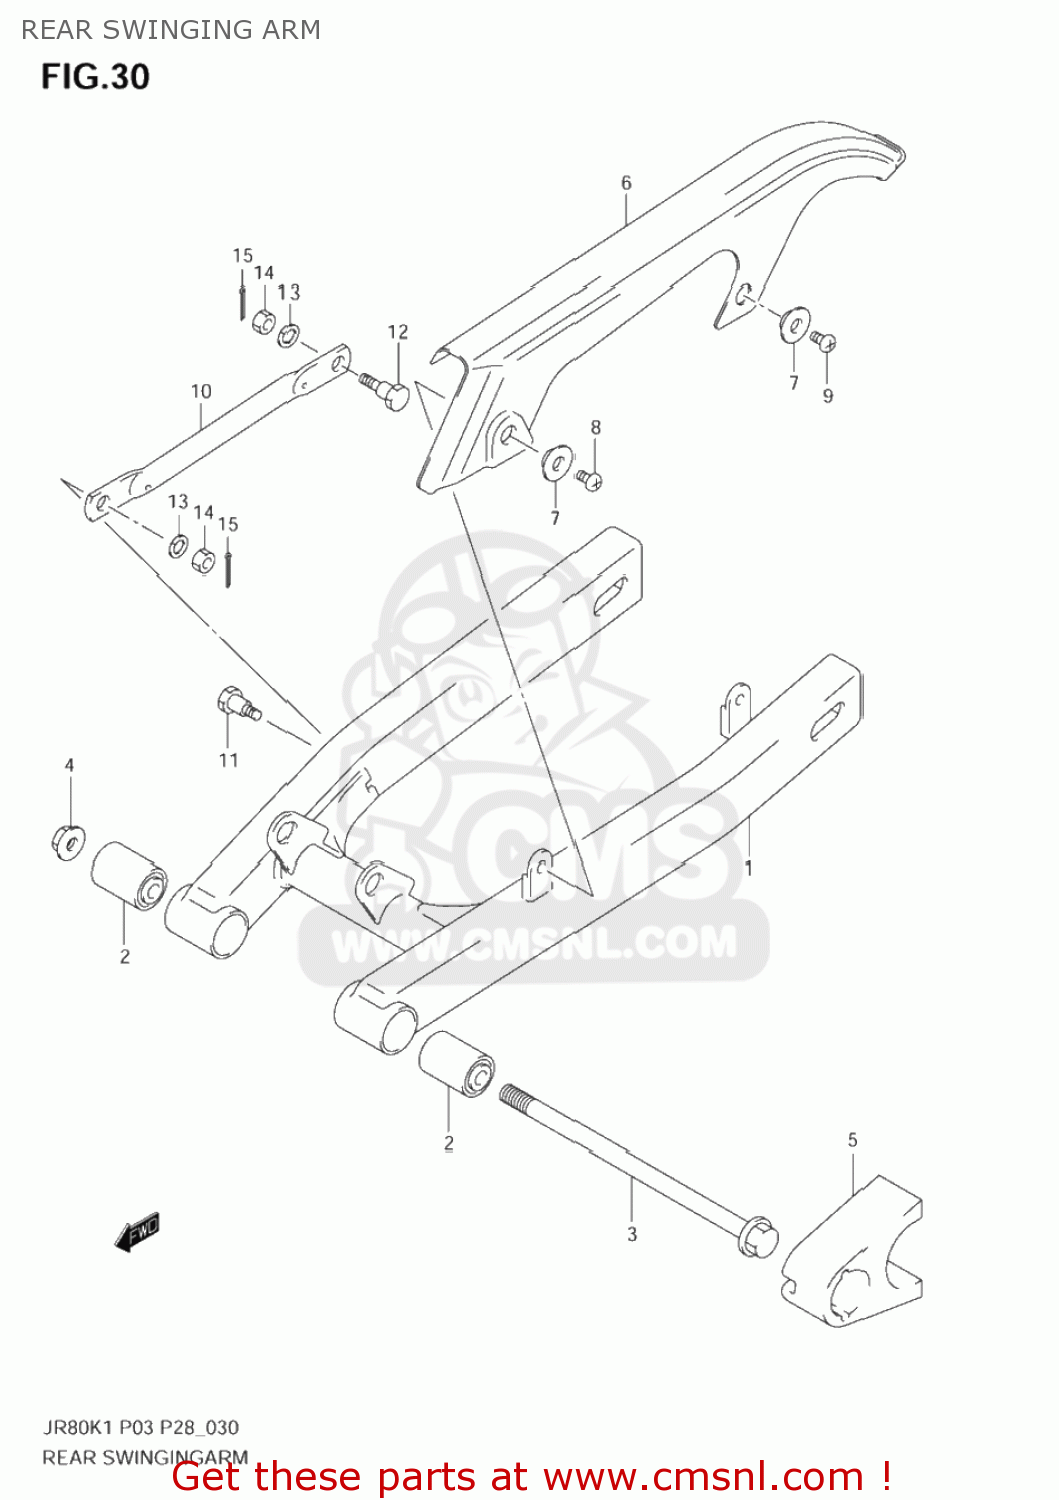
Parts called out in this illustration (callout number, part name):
1	SWINGINGARM ASSY,RR
2	BUSH
3	SHAFT,RR SWINGINGARM PIVOT
4	NUT
5	BUFFER,CHAIN TOUCH DEFENSE
6	CASE,CHAIN
7	WASHER
8	SCREW
9	SCREW
10	TORQUELINK,RR
11	BOLT(8X22)
12	BOLT(8X26.5)
13	LOCK WASHER
14	NUT
15	PIN 20X20
